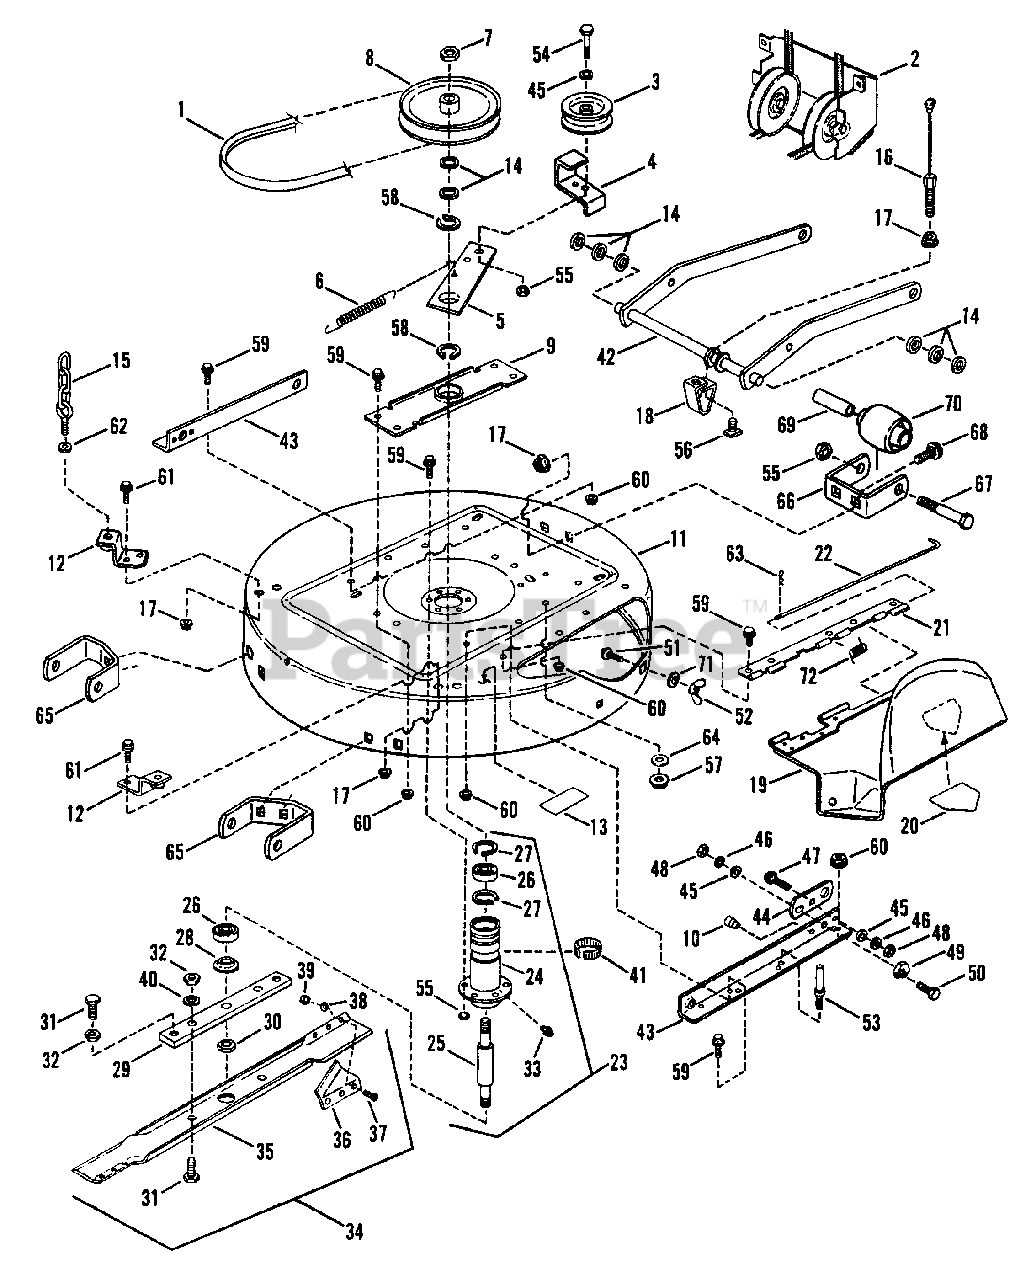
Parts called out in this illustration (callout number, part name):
1	BELT, 33" Mower Drive (A101)
2	ASSEMBLY, Mule Drive
3	PULLEY, Idler (Flat) (4.12 O.D.)
4	GUIDE, Belt
5	ARM, Idler
6	SPRING, Belt Tension
7	NUT, 3/4-16 Hex Jam
8	PULLEY, 8" O.D.
9	BRACE, Spindle
10	BUMPER BUTTON
11	DECK, 33" Cutter
12	ASY, Bracket Rear Lift
13	DECAL, Caution, (Deflector/Adapter)
14	WASHER, Shim
15	ASSEMBLY, 3/8 Bolt-Chain
16	CABLE, Front Lift
17	NUT, 5/16 18 Hex Fl. Lock
18	BRACKET, Front Lift Hanger
19	ASSEMBLY, Deflector
20	DECAL, Danger (Cut Finger)
21	HINGE, Side Chute
22	PIN, Hinge
23	ASSEMBLY, Spindle
24	HOUSING, Spindle
25	SPINDLE, Deck, 7.75"
26	BEARING, Spindle
27	RING, Retaining
28	WASHER, Spindle
29	HOLDER, Blade
30	NUT, 5/8-18 Hex Ctr. Lock
31	SCREW, 1/2-20 x 1" Hex Head Cap, Grade 5
32	NUT, 1/2-20 Hex Jam
33	FITTING, Lube (Press fit for .187 hole-no ball)
34	ASSEMBLY, Blade & Air Lift
35	BLADE, 33" Mower Deck
36	AIR-LIFT
37	SCREW, 5/16-24 Machine
38	WASHER, 5/16 Internal Tooth Lock
39	NUT, 5/16-24 Hex
40	WASHER, 1/2" Internal Tooth Lock
41	RING, Tolerance
42	WELDMENT, Front Lift Arm
43	RAIL- 33"
44	LINK- ADJUSTMENT
45	WASHER, 3/8" Flat
46	WASHER, 3/8 Split Lock
47	3/8-16 BOLT, x 3/4" Carriage
48	NUT, 3/8-16 Hex
49	RING, Adjustment
50	SCREW, 3/8-16 x 1" HHC
51	BOLT, 5/16-18 x 3/4" Short Neck Carriage, Grade 5
52	WING-NUT, 5/16-18
53	STUD, Deck Stop
54	SCREW, 3/8-24 x 1-1/2" Hex Head Cap, Grade 2
55	NUT, 3/8-24 Hex Center Lock
56	T-NUT, 5/16-18
57	NUT, 3/8-24 Hex
58	RING, 2" External Retaining
59	BOLT, 3/8-16 x 3/4" Hex Flange Lock
60	NUT, 3/8-16 Hex Flange Lock
61	BOLT, 5/16-18 x 1/2" Hex Flange Lock, Grade 5
62	NUT, 3/8-16 Hex Jam
63	PIN, Hair Cotter
64	WASHER, 3/8 Int. Tooth Lock
65	BRACKET, Gage Wheel (Rear)
66	BRACKET, Front Gage Wheel
67	SCREW, 3/8-24 x 3-3/4" Hex Head Cap Grade 5
68	BOLT, 5/16-18 x 1/2" Square Neck Carriage, Gr. 5
69	SPACER
70	WHEEL, Gage
71	WASHER, 5/16 Flat
72	SPRING, Hinge
